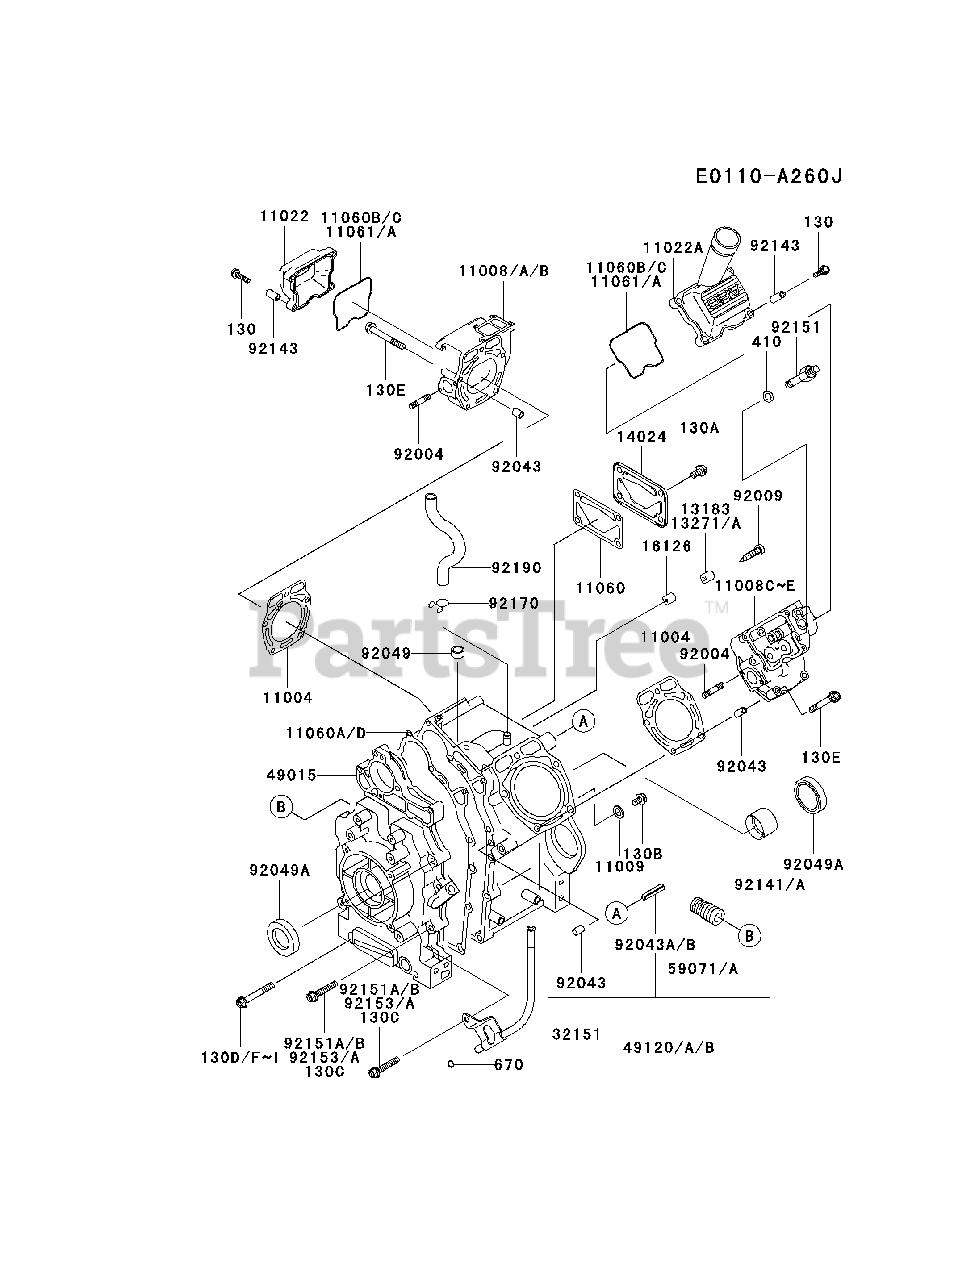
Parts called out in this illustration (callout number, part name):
130	BOLT-FLANGED,6X25
130A	BOLT-FLANGED,8X16
130B	BOLT-FLANGED,8X12
130E	BOLT-FLANGED,8X65
130H	BOLT-FLANGED,8X60
410	W-PLAIN-S,8MM
670	O RING,10MM
92151A	BOLT,8X45
